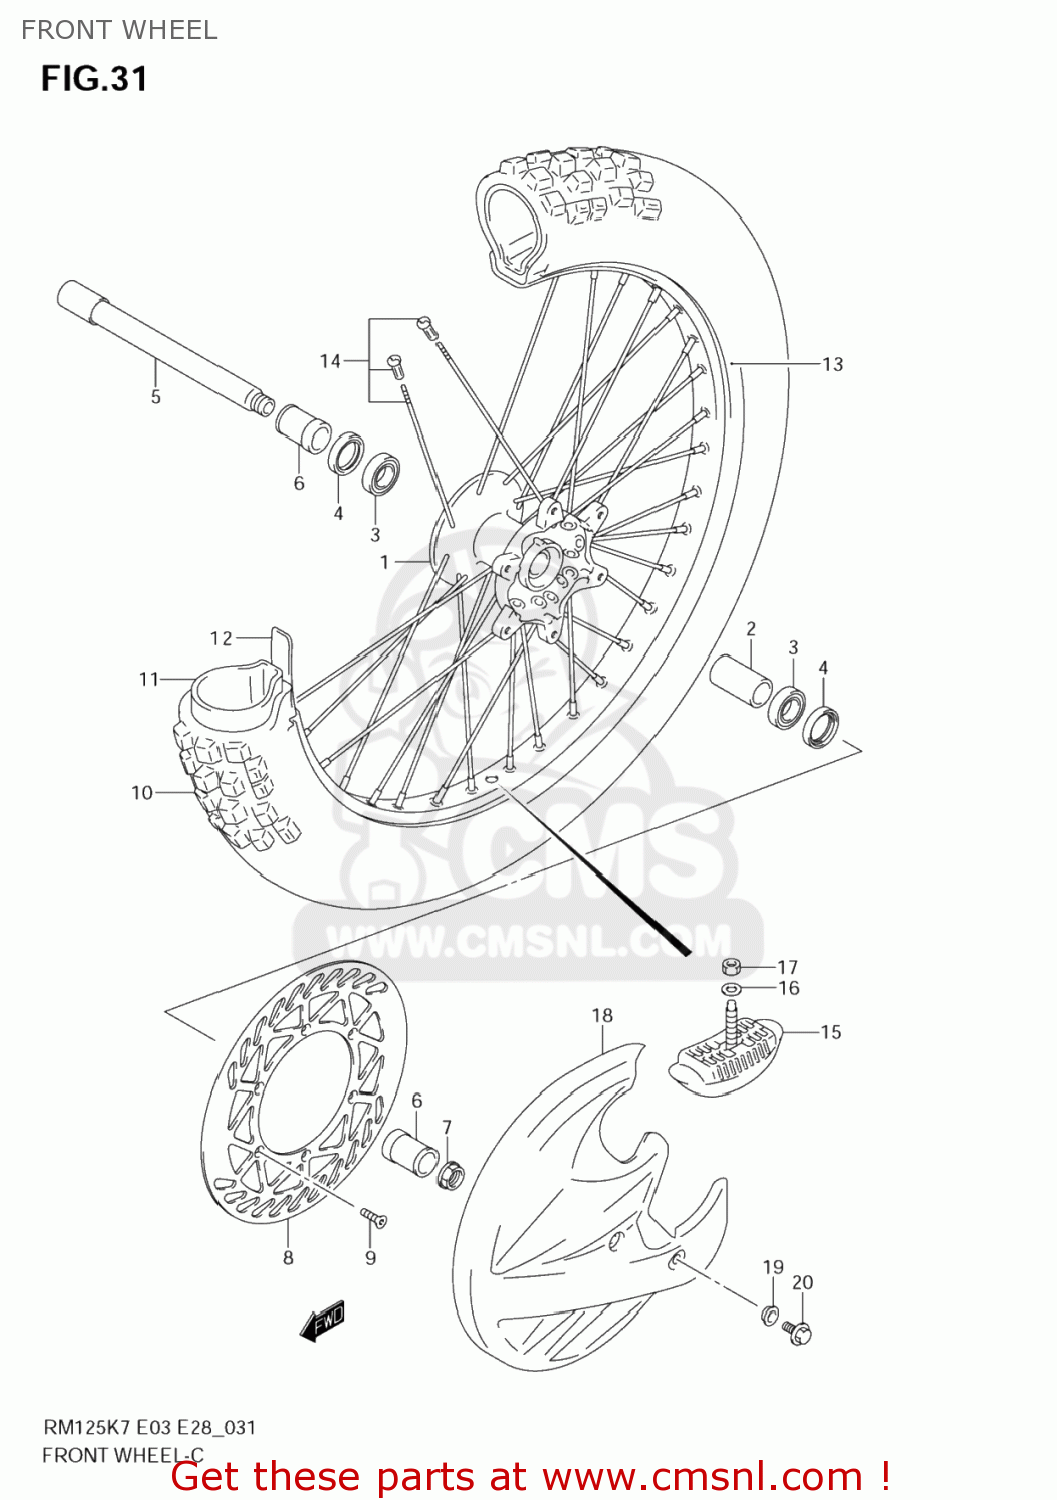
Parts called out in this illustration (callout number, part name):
1	HUB,FR WHEEL
2	SPACER,FR HUB BEARING
3	BEARING
4	SEAL,OIL(28X37X7)
5	AXLE,FR
6	SPACER,FR AXLE
7	NUT
8	DISC,FR BRAKE
9	SCREW(6X18)
10	TIRE,FR(80/100 21)
11	TUBE ASSY,WHEEL INNER
12	PROTECTOR,WHL INR TUBE
13	RIM,FR WHEEL(1.60X21)
14	SPOKE SET,FR WHEEL
15	STOPPER,BEAD
16	WASHER
17	NUT
18	COVER,FR BRAKE DISC
19	WASHER
20	BOLT(6X12)
